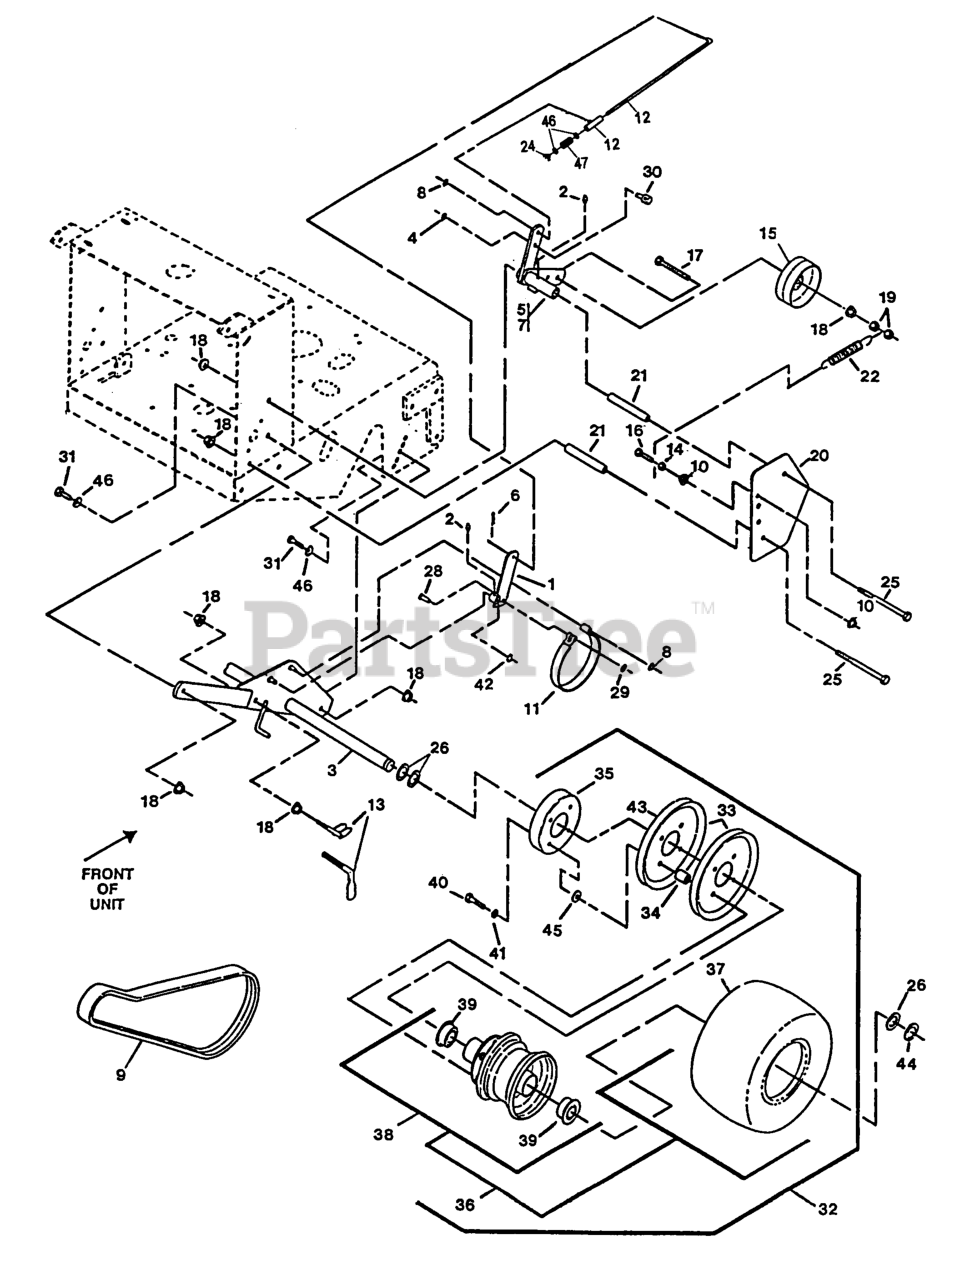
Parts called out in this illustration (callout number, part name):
6	PIN-COTTER
9	BELT,WHEEL DRIVE
11	BAND-BRAKE
13	SCRAPER
15	IDLER-WHEEL, DRIVE
20	SHIELD-WHEEL, DRIVE
21	SPACER-SHIELD
22	SPRING-EXTENSION
23	LINKAGE-BRAKE
24	WINGNUT-NYLOCK
26	WASHER-SPACER
28	PIN-CLEVIS
29	RING-RETAIN,PUSH,EXT,FLAT
30	SWIVEL-SHORT, ADJUSTABLE
33	SHEAVE-WHEEL, DRIVE
34	SPACER-SHEAVE, WHEEL
35	DRUM-BRAKE
38	WHEEL AND HUB ASM
39	BEARING-FLANGED
41	WASHER-LOCK
43	SHEAVE-WHEEL, DRIVE
44	RING-SNAP
47	SPRING-COMPRESSION
